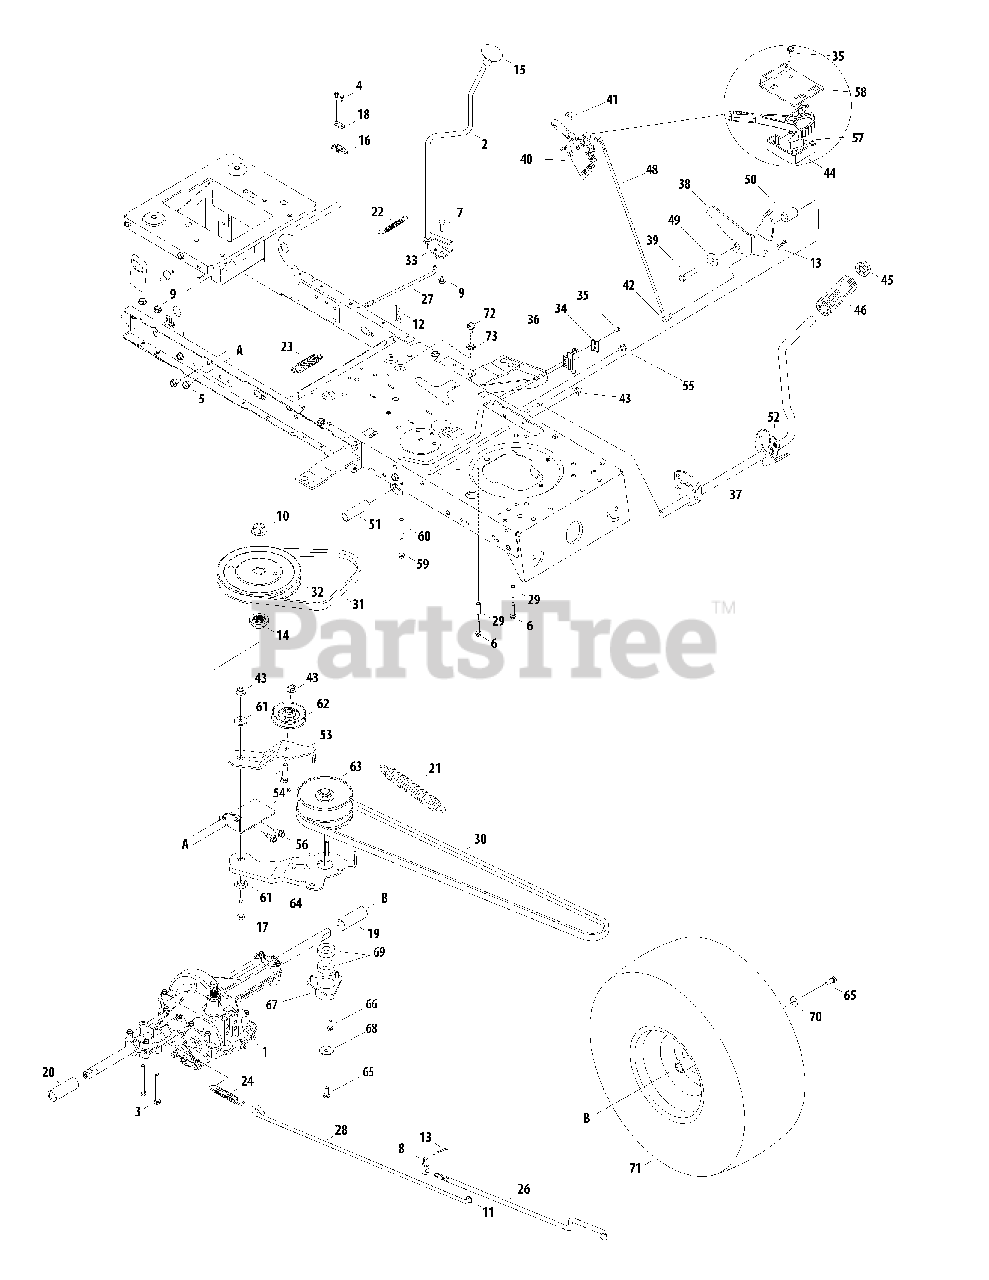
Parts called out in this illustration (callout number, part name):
1	Transmission Ass’y
2	Shift Lever Ass’y
3	Hex Scr 5/16-18 x 2.75
4	Hex Wash HD AB S-Tapp Scr #8-.50
5	S-Tapp Scr 5/16-18 x .75
6	Hex Bolt 1/4-20 x 1.25
7	Hex Bolt 5/16-18 x .75" Lg. Gr. 5
9	Flange Locknut 5/16-18 Gr. F, Nylon
11	Cotter Pin 3/32 dia x 1.00 Lg.
12	Cotter Pin
13	Bow Tie Cotter Pin
14	Pulley Hub 5/8" Spline
16	Short Spring Switch
17	Screw, 3/8-16 x 1.75
18	Insulator Nut Plate
19	Sleeve, .758 x .821 x 3.3125
20	Sleeve, .758 x .821 x 2.4375
21	Spring, Extension, .94 OD x 6.75
22	Spring, Extension, .38 OD x 3.25 LG
23	Spring, Extension, .80 OD x 3.28
24	Ext. Spring .59 OD x 4.00 Lg.
25	Flat Washer .344 ID x .625 OD x .063
26	Control Rod, Variable Speed
29	Spacer .260 x .375 x 1.030 Lg.
31	Belt
32	Pulley, V-Type, 7.25 dia.
33	Shift Bracket, Adjustable
34	Switch Plate
35	Hex AB-Tap Scr #10 X .50" Lg.
36	Interlock Switch
37	Drive Pedal Assembly
38	Latch Ass’y, Engagement (RMC)
39	Hex Screw 3/8-16 x 2.0 Gr. 5
40	6 Speed Shift Control Ass'y
40	7 Speed Shift Control Ass'y
41	Screw, 1/4-20 x .5
42	Adjustment Ferrule
43	Flange Lock-Nut 3/8-16 Gr. F Nylon
44	Control Cover
45	Push Cap 5/8" Dia Rod
46	Foot Pad
48	Speed Selecter Control Rod
49	Flat Washer .411 ID x 1.25 OD x .10
50	Flange Spacer .390 x .671 x 1.095
51	Spacer .630 ID
52	Pedal Support Bracket
53	Idler Bracket
54	Transmission Torque Bracket
55	Self-tapping Screw 5/16-18 x .625
56	Hex Wash. Hd. Scr. 5/16-18 x .75 Lg.
57	Shift Lever Spring
58	Control Bracket
59	Screw, 1/4-20 x 1.625
60	Spacer, .260 x .372 x 1.420
61	Shoulder Spacer
63	Variable Speed Pulley Ass’y 4.75 OD
64	Variable Speed Bracket Ass’y
65	Hex L-Screw 5/16-24 x 0.75 Gr. 5
66	Hex Scrw 1/4-20 x 1.5
68	Flat Washer .22 ID x 1.25
69	Ball Bearing 17 x 40 x 12
70	Cupped Washer .345 ID x .88 OD x .060
71	Wheel Assembly Complete, 20 x 8 x 8
72	Hex Wash S-Tapp Scr 1/4-20 x .50
73	Lockwasher 1/4"
